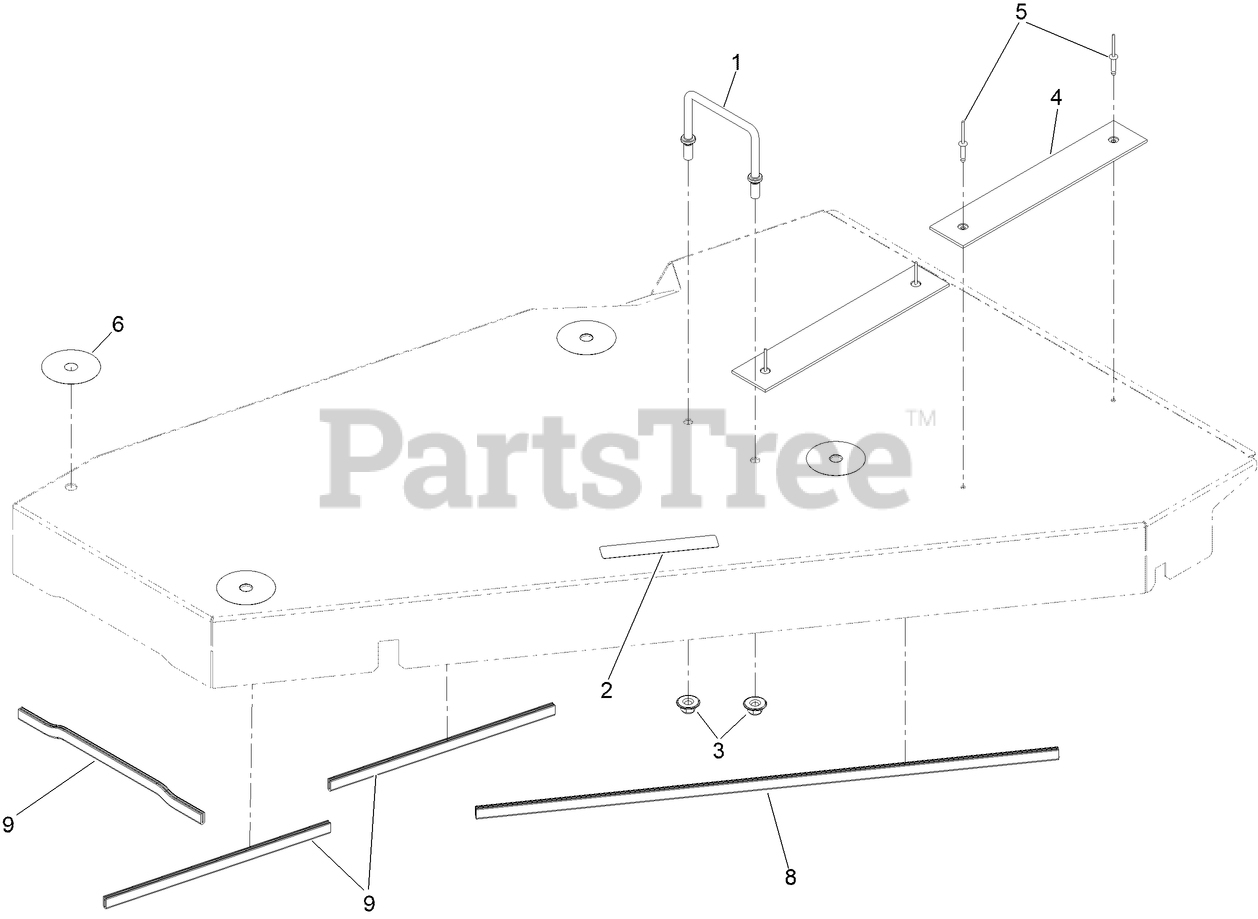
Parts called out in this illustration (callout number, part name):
1	WIREFORM-COVER
2	DECAL-NO STEP
3	Nut-Nyloc 3/8-16 Flg
4	Plate-Uhmw 2"
5	Rivet-Pop
6	DECAL-SCRATCH COVER
8	GUARD EDGE
9	GUARD-EDGE
